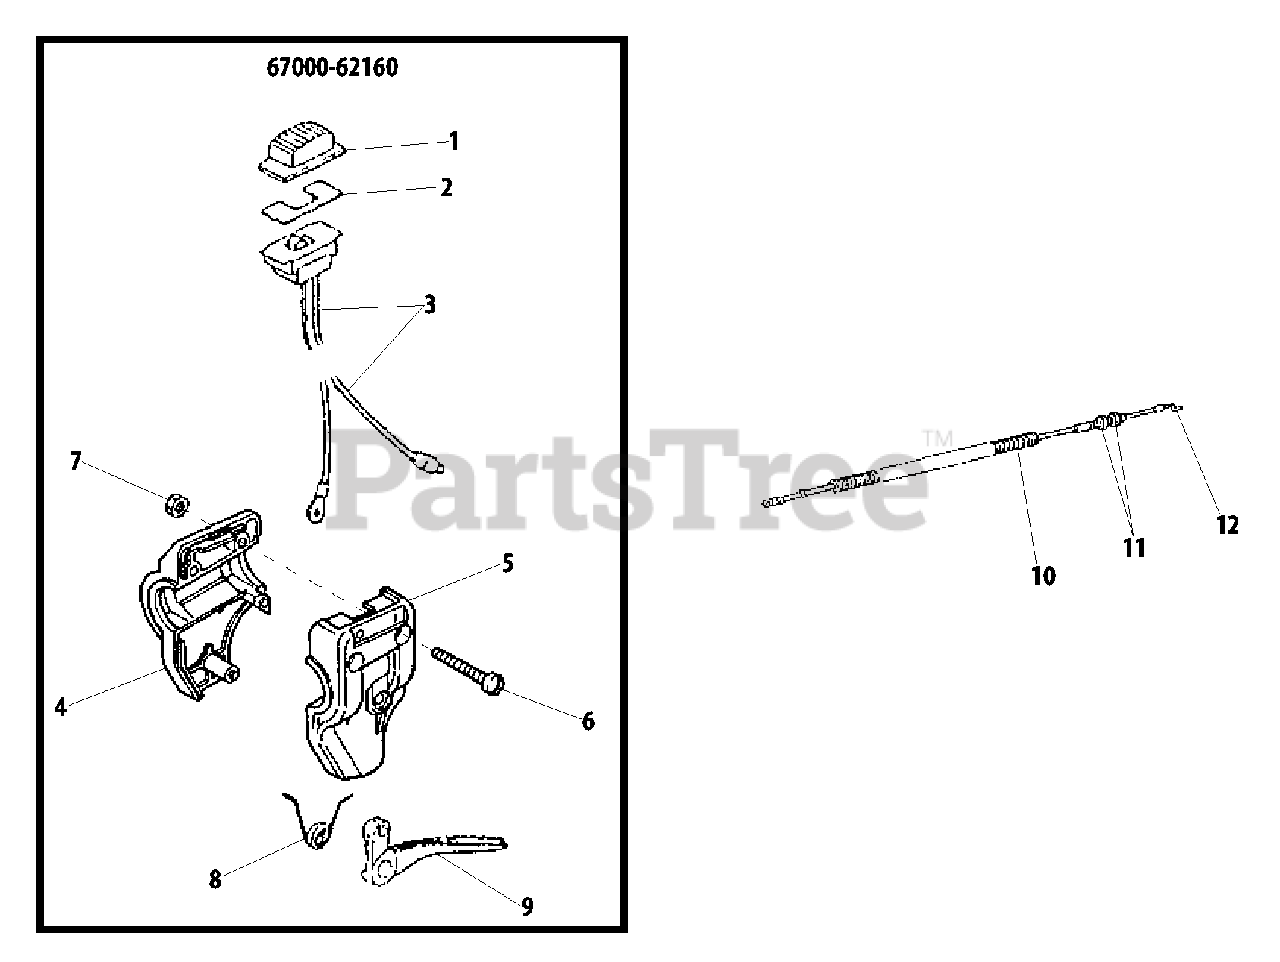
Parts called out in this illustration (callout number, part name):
1	KNOB, SWITCH
2	PLATE, SWITCH
3	SWITCH, ON-OFF
4	CONTROL HANDLE - RIGHT
5	CONTROL HANDLE - LEFT
6	SCREW
7	NUT M5
8	SPRING, RETURN
9	TRIGGER, THROTTLE
10	TUBE, FLEXIBLE
11	NUT M6
12	CABLE, THROTTLE
67000-62160	THROTTLE CONTROL ASSY
